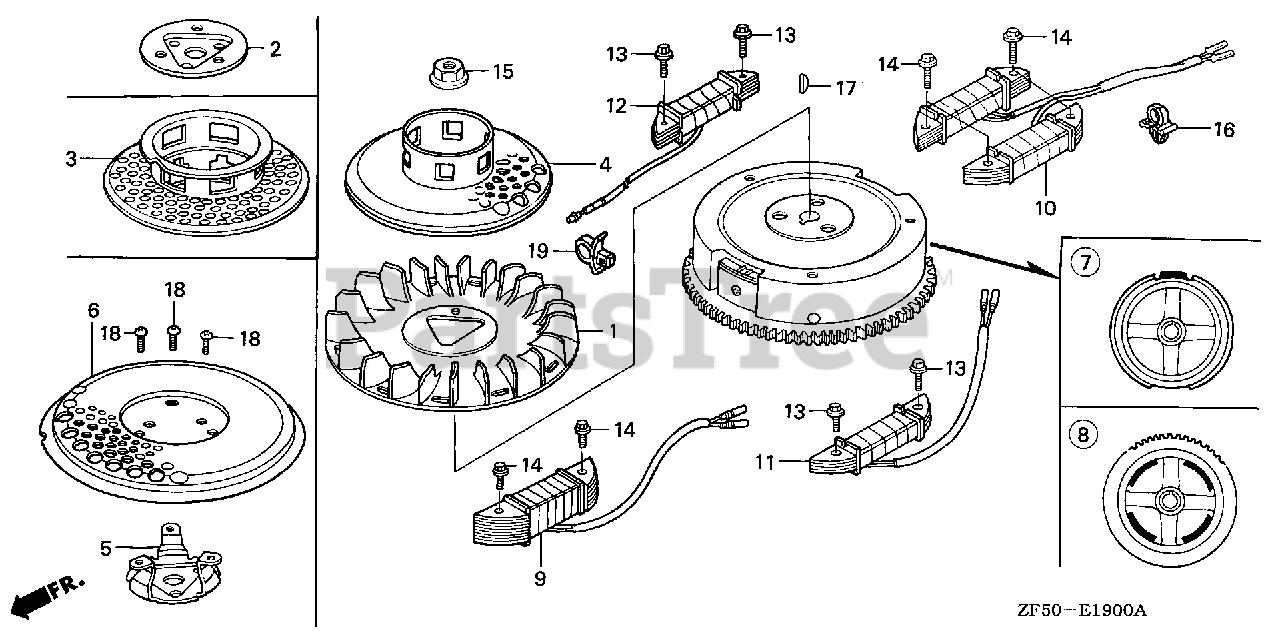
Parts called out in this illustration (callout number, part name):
1	FAN, COOLING
3	PULLEY, STARTER Use up to Engine SN 2013098.
4	PULLEY, STARTER (SCREEN GRID)
8	FLYWHEEL (SEL-4POLE)
11	COIL ASSY., CHARGE (4A)
13	BOLT, FLANGE (6X28) (CT200)
15	NUT, SPECIAL (16MM)
17	KEY, SPECIAL WOODRUFF (25X18)
